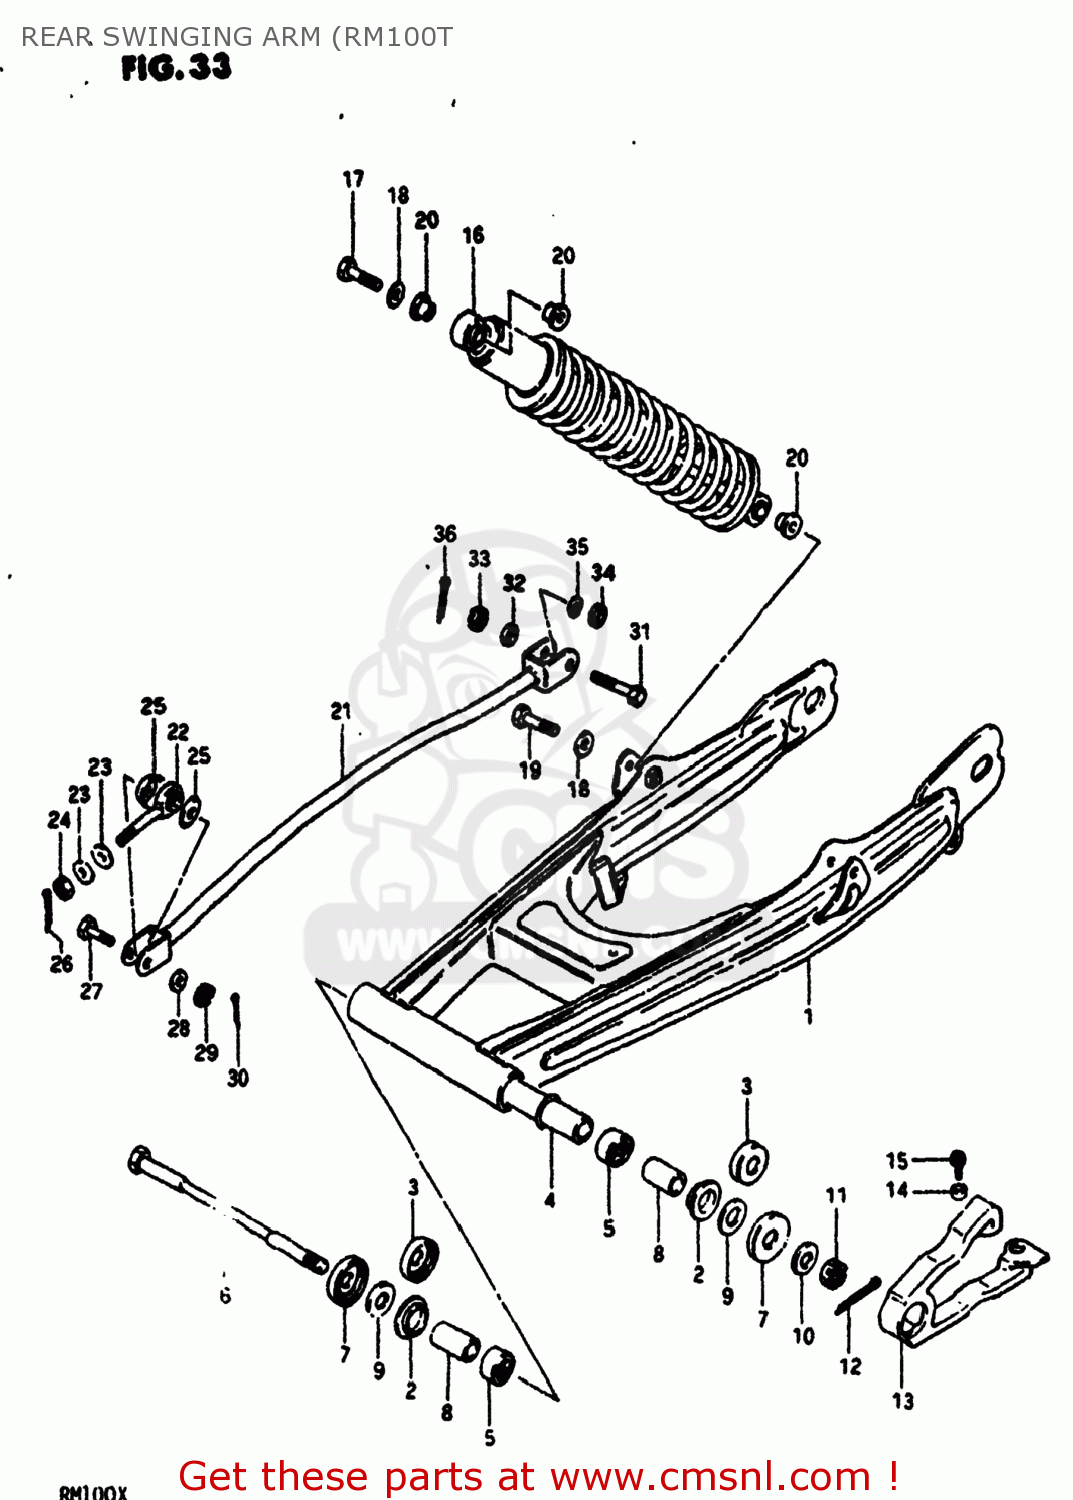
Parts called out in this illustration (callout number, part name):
1	SWING ARM ASSEMBLY,REAR
2	BUSH,RR SWINGINGARM PIVOT
3	SEAL,OIL(17X24X3)
4	SPACER
5	ROLLER BEARING (17X24X2
6	SHAFT,RR SWINGINGARM PIVOT
7	COVER,REAR SWING ARM DUST
8	SPACER,RR SWGARM PIVOT
9	WASHER
10	WASHER
11	NUT, REAR AXLE
12	COTTER PIN
13	BUFFER,CHAIN TOUCH DEFLECTOR
14	SPACER (5.5X8X4)
15	SCREW,CHAIN TOUCH DEFEND
16	ABSORBER ASSEMBLY,REAR SHOCK
17	BOLT
18	WASHER
19	BOLT
20	SPACER,RR SHK ABS INNER
21	TORQUE LINK,REAR
22	BEARING
23	WASHER
24	NUT
25	26
26	PIN
27	BOLT 8X28
28	WASHER
29	NUT 8MM
30	PIN 20X20
31	BOLT 8X35
32	WASHER
33	NUT 8MM
34	35
35	WASHER (8.5X16X2.6)
36	PIN 20X20
